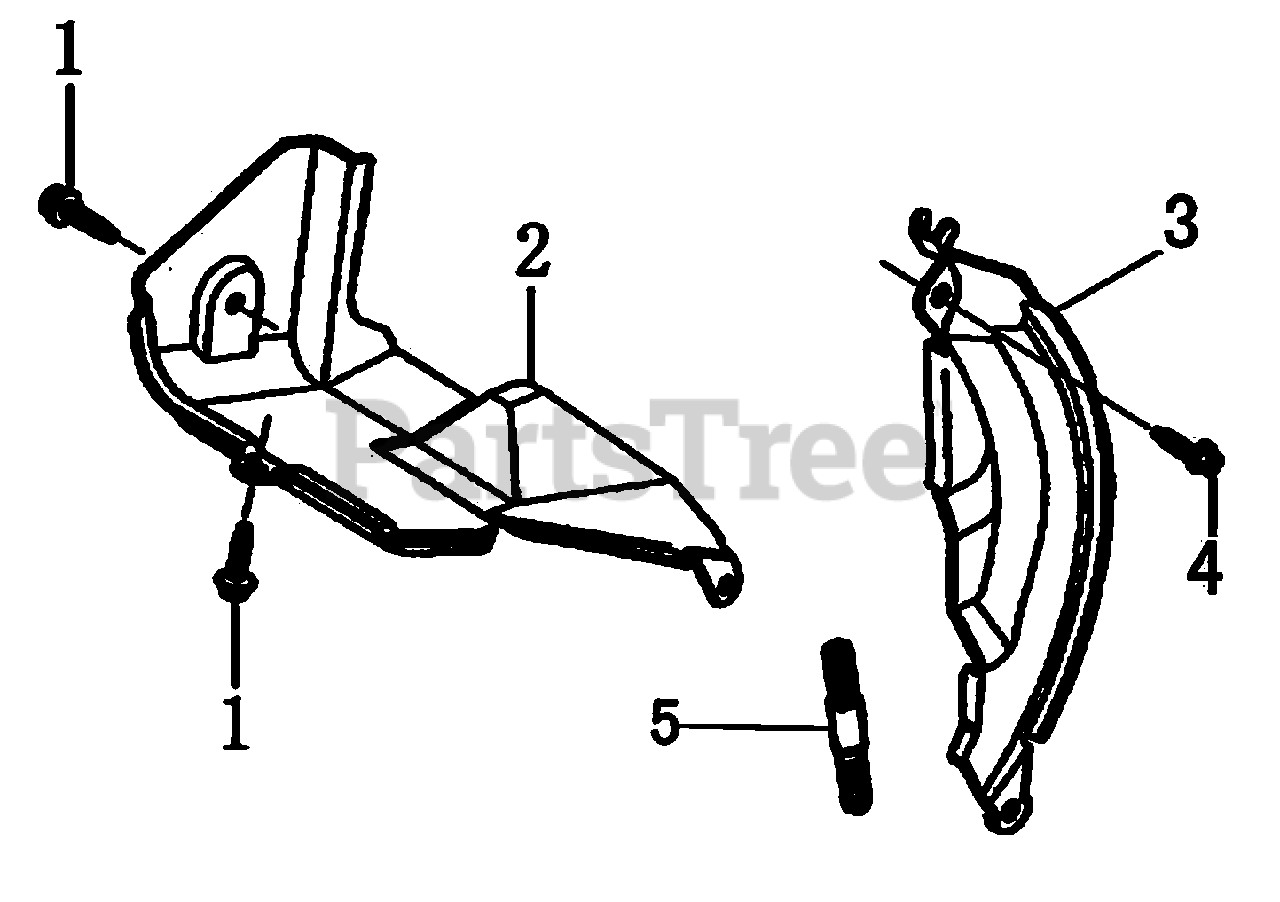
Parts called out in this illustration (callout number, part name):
1	BOLT, FLANGE 6X8
2	PLATE, AIR GUIDE
3	PLATE, SIDE
4	BOLT, FLANGE , 6X20
5	BOLT, STUD
